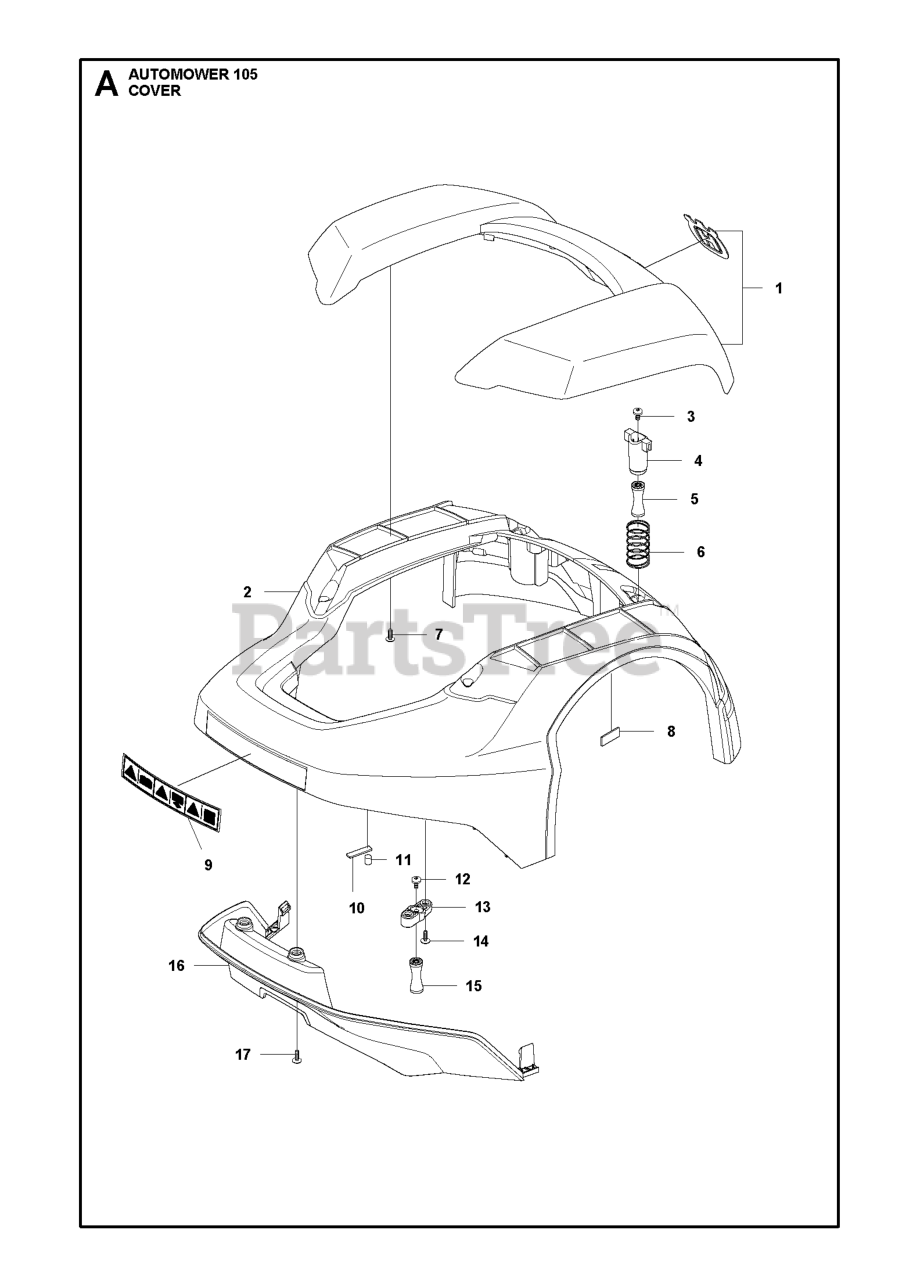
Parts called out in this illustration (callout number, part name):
3	SCREW ISO 14583 M5X12 T25 A2-7
4	BRACKET COLUMN FRONT USE WITH
5	DAMPER RUBBER 40 SHORE
6	SPRING LIFT SENSOR L = 35 MM
7	SCREW 14MM
8	MAGNET LIFT SENSOR
10	PLATE CARRIER MAGNET
11	MAGNET COLLISION SENSOR
12	SCREW ISO 14583 M5X12 T25 A2-7
13	SUPPORT CLAMP USE WITH M5 X 1
14	SCREW 14MM
15	DAMPER RUBBER 40 SHORE
17	SCREW SILVER 10MM
